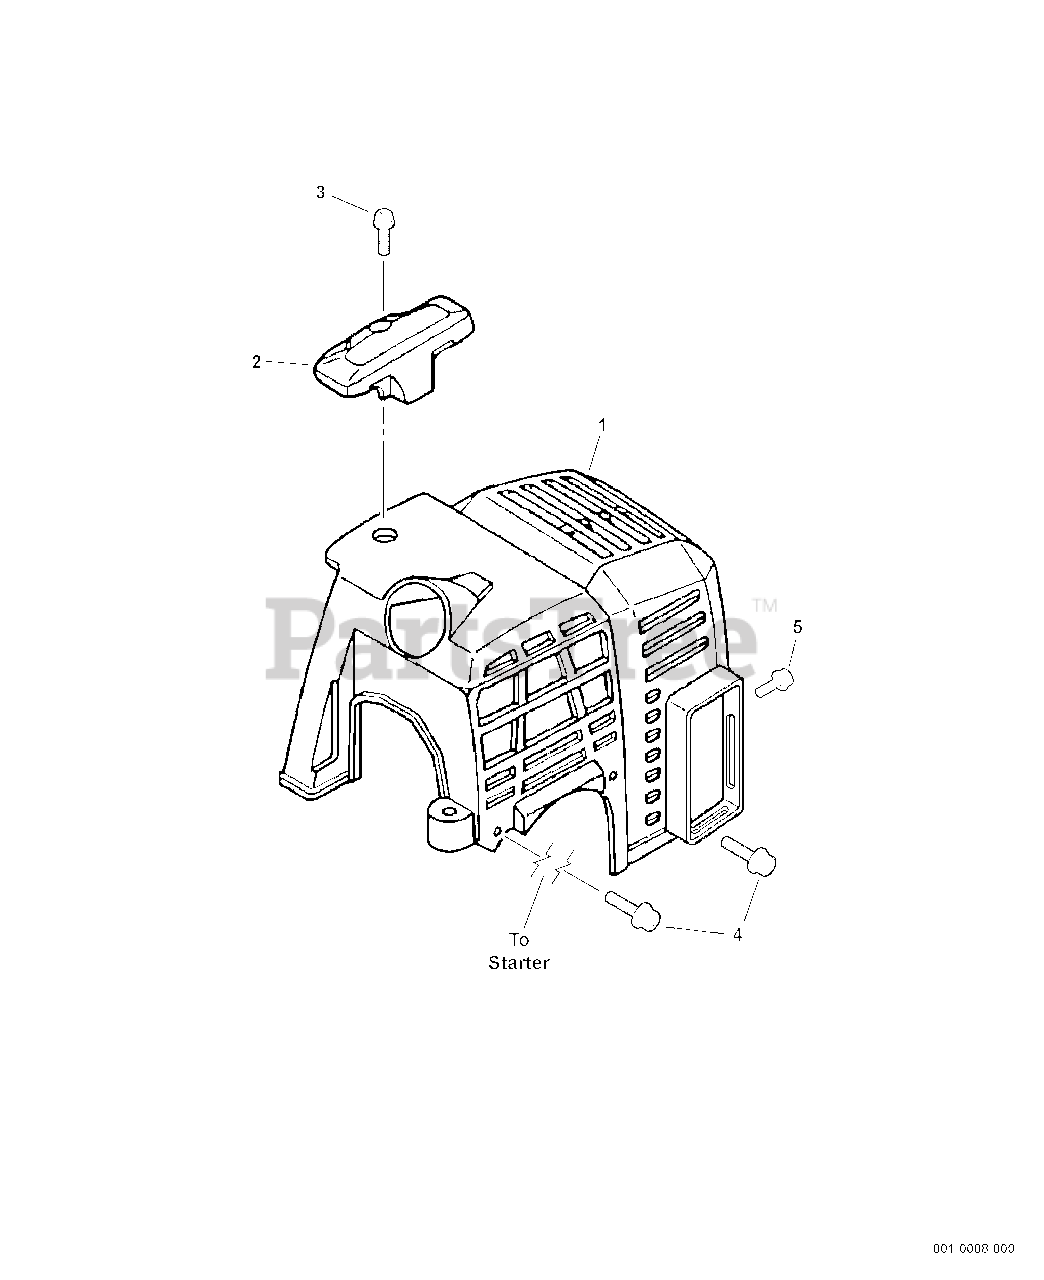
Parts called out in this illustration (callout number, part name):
1	COVER, ENGINE
2	GUARD, TOP
3	SCREW 5×16
4	BOLT 4×16
5	BOLT 4×8
